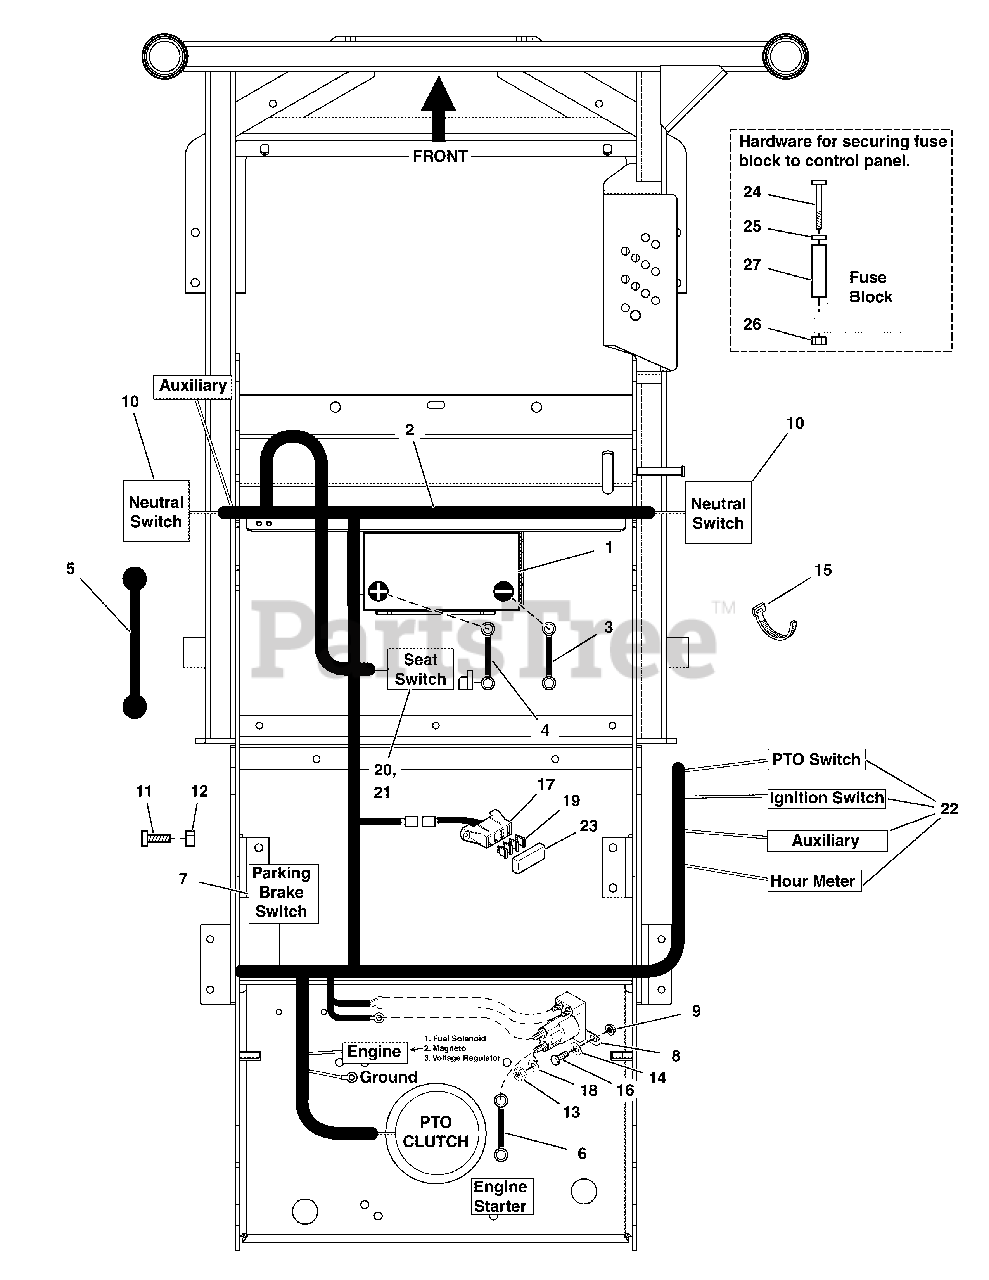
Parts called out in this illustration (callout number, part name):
1	BATTERY
2	WIRE HARNESS
3	BATTERY CABLE, NEG, 30, 1/4-5/16
4	CABLE, #6 X 30" LONG, Ring Terminal
5	STRAP, Rubber, 13"
6	BATTERY CABLE, POSITIVE, 8
7	SWITCH, Push Button, N.O . N.C, Double Pole, Grey
8	SOLENOID-4 POLE 12 VOLT DC (TROMBETTA)
9	NUT, Serrated, Flange, 1/4-20, GR5
10	SWITCH, LOW PROF, NC/NO
11	SCREW- #10-24 X 1/2 ROUND PHILLIPS
12	NUT, Hex, #10-24
13	NUT, HEX JAM, 5/16-24 (SV)
14	WASHER, Flat, 1/4
15	TIE, SELF-LOCKING, 12"
16	CAPSCREW, Hex Head, 1/4-20 x 5/8, GR5
17	WIRE HARNESS FUSE BL
18	WASHER, LIGHT LOCK, 5/16 (SV)
19	FUSE, ATO, 20 AMP (SV)
20	SWITCH, NC, W/ BOLT-IN BASE
21	SWITCH, NC, W/ TWIST-IN BASE
22	Refer to: Instrument Control Panel Group
23	COVER, VINYL FUSEBLOCK
24	SCREW, #10-24 X 2 ROUND PHILLIPS
25	WASHER, #10 SAE
26	NUT, #10-24 HEX NYLON LOCK
27	SPACER, .20 X .38 X 1.25
